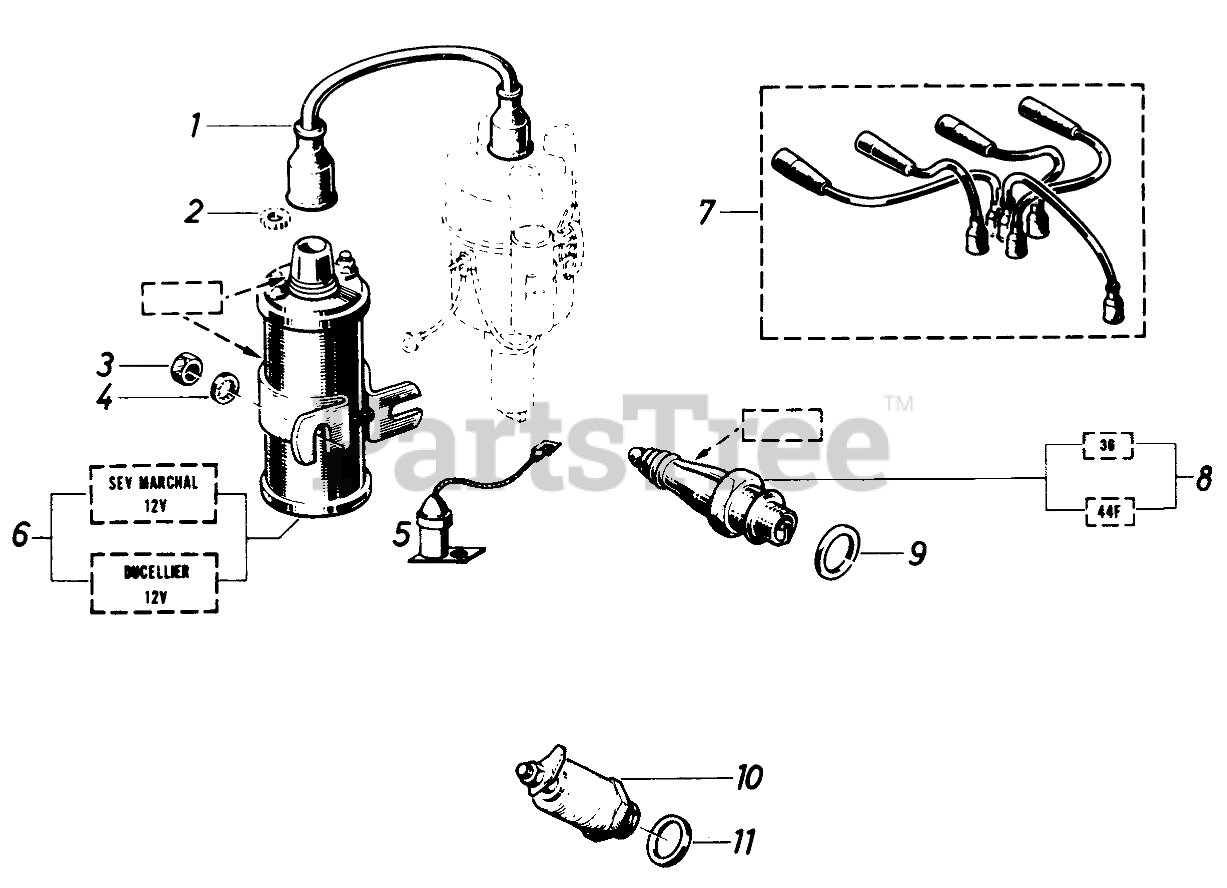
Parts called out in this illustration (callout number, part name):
1	Ignition Cable
2	Washer
4	Lock Washer
5	Condenser
6	Ignition Coil
7	Ignition Cable Set
8	Spark Plug
9	Gasket
10	Oil Pressure Switch
11	Gasket
